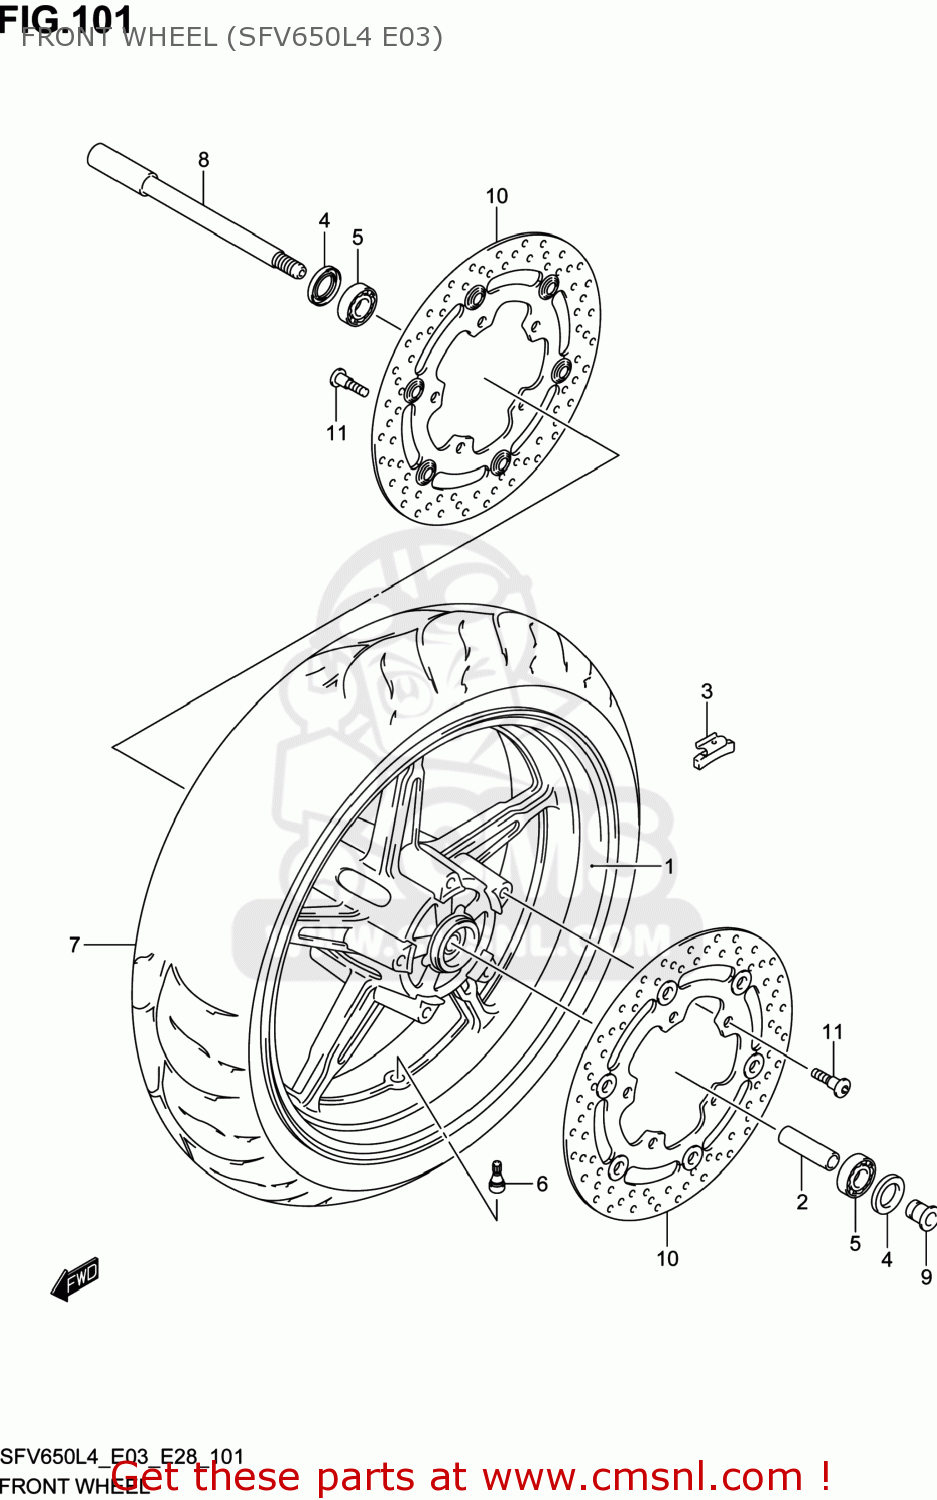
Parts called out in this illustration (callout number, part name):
1	WHEEL,FR(17M/CXMT3.50)
2	SPACER,FR HUB BEARING
3	BALANCER,WHEEL(10G)
4	SEAL,OIL(22X40X7)
5	BEARING
6	VALVE ASSY,WHEEL RIM(TR412)
7	TIRE,FRONT(120
8	AXLE,FR
9	SPACER,FR AXLE,L
10	DISC,FR BRAKE
11	BOLT(8X21)
